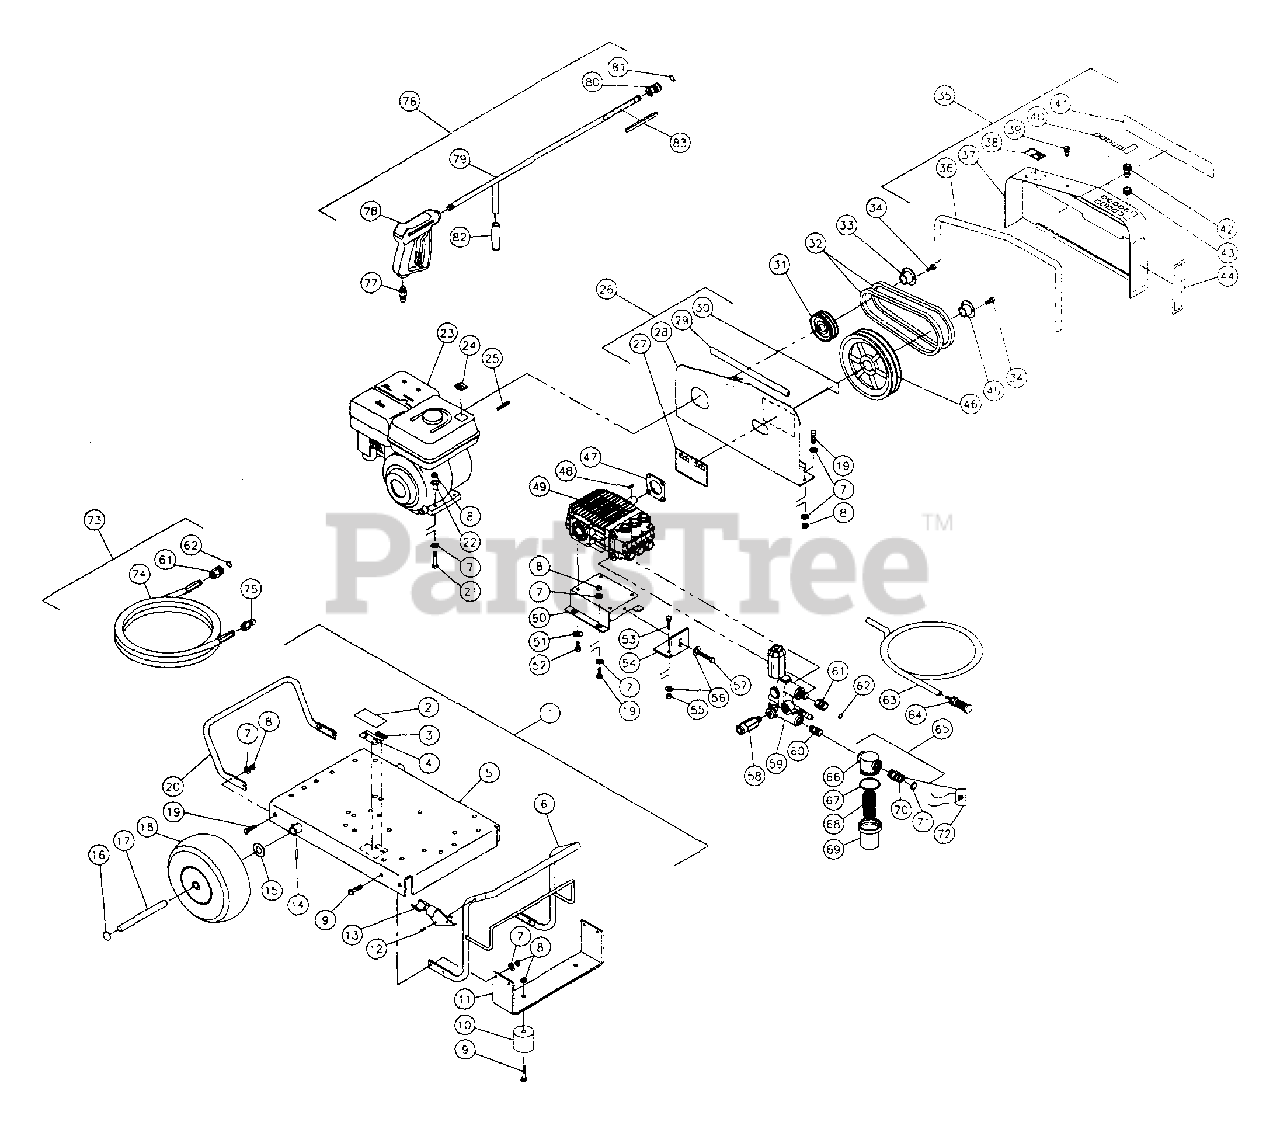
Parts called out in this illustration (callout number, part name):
1	Base Plate Assembly
2	Decal - Clear Laminate
3	Decal - Cold Water Serial Number
4	Decal - Silver Sticker
5	Base Plate
6	Handle - Front
10	Isolator
11	Underbracket
13	Wand holder - Plastic
14	Roll Pin
20	Handle - Rear
22	Engine Shim
24	Decal - Caution Allow to Cool
26	Beltguard Back Assembly
27	Decal - Caution/Warning Statements
28	Beltguard Back - Small
29	Edging (1" x 13.5")
30	Decal - Warning Beltguard in Place
31	Sheave 2AK39H
32	Belt - Engine A X 36
34	Bolt - with bushing
35	Beltguard Cover Assy
36	Edging (1" x 34.5")
37	Beltguard Cover - Small
38	Decal - Warning Muffler Hot
39	Fastener
40	Decal - Nozzles 0ø, 15ø, 25ø, 40ø
41	Decal -
42	Nozzle - 0004
44	Operating Instructions
46	Sheave 2AK84H
47	Isolator - Pump
48	Key - with pump
50	Pump Bracket
51	Washer - with pump
52	Bolt - with pump
54	Brace Tightener
58	Heat Dump Valve
59	Unloader
60	Hex Nipple
61	Quick Connect Socket
63	Detergent Hose (4')
64	Detergent Strainer
65	Strainer Complete
66	Strainer Cap
67	Strainer Gasket
68	Strainer Steel Screen
69	Strainer Bowl
70	Garden Hose Swivel
71	Garden Hose Gasket
72	Tag - Water Supply Inlet
73	Pressure Hose Assy
74	Pressure Hose 3/8" x 50' 3000 PSI
75	Quick Connect Plug - Female 3/8"
76	Gun/Wand Assy
77	Quick Connect Plug - Male 3/8"
79	Wand with 36" Handle
80	Quick connect socket 1/4"
82	Handle Grip for Wand
83	Decal - Warning Risk of Injection
